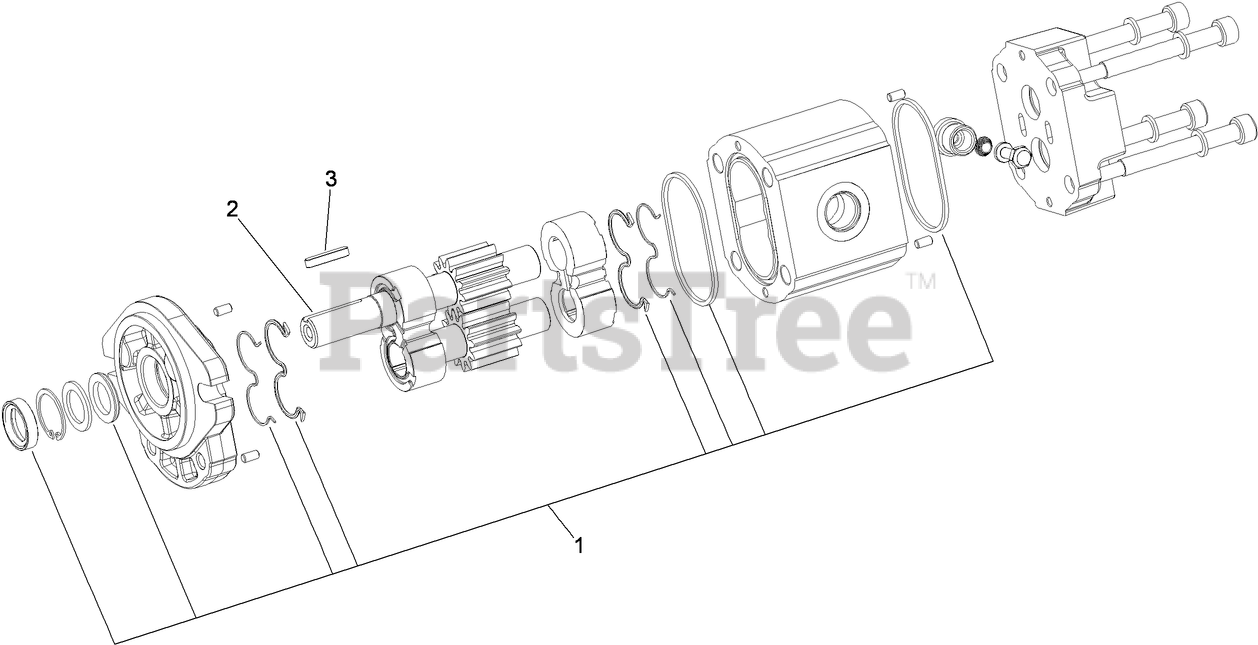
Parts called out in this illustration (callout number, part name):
1	SEAL KIT
2	SHAFT-MOTOR
3	KEY-SQUARE
